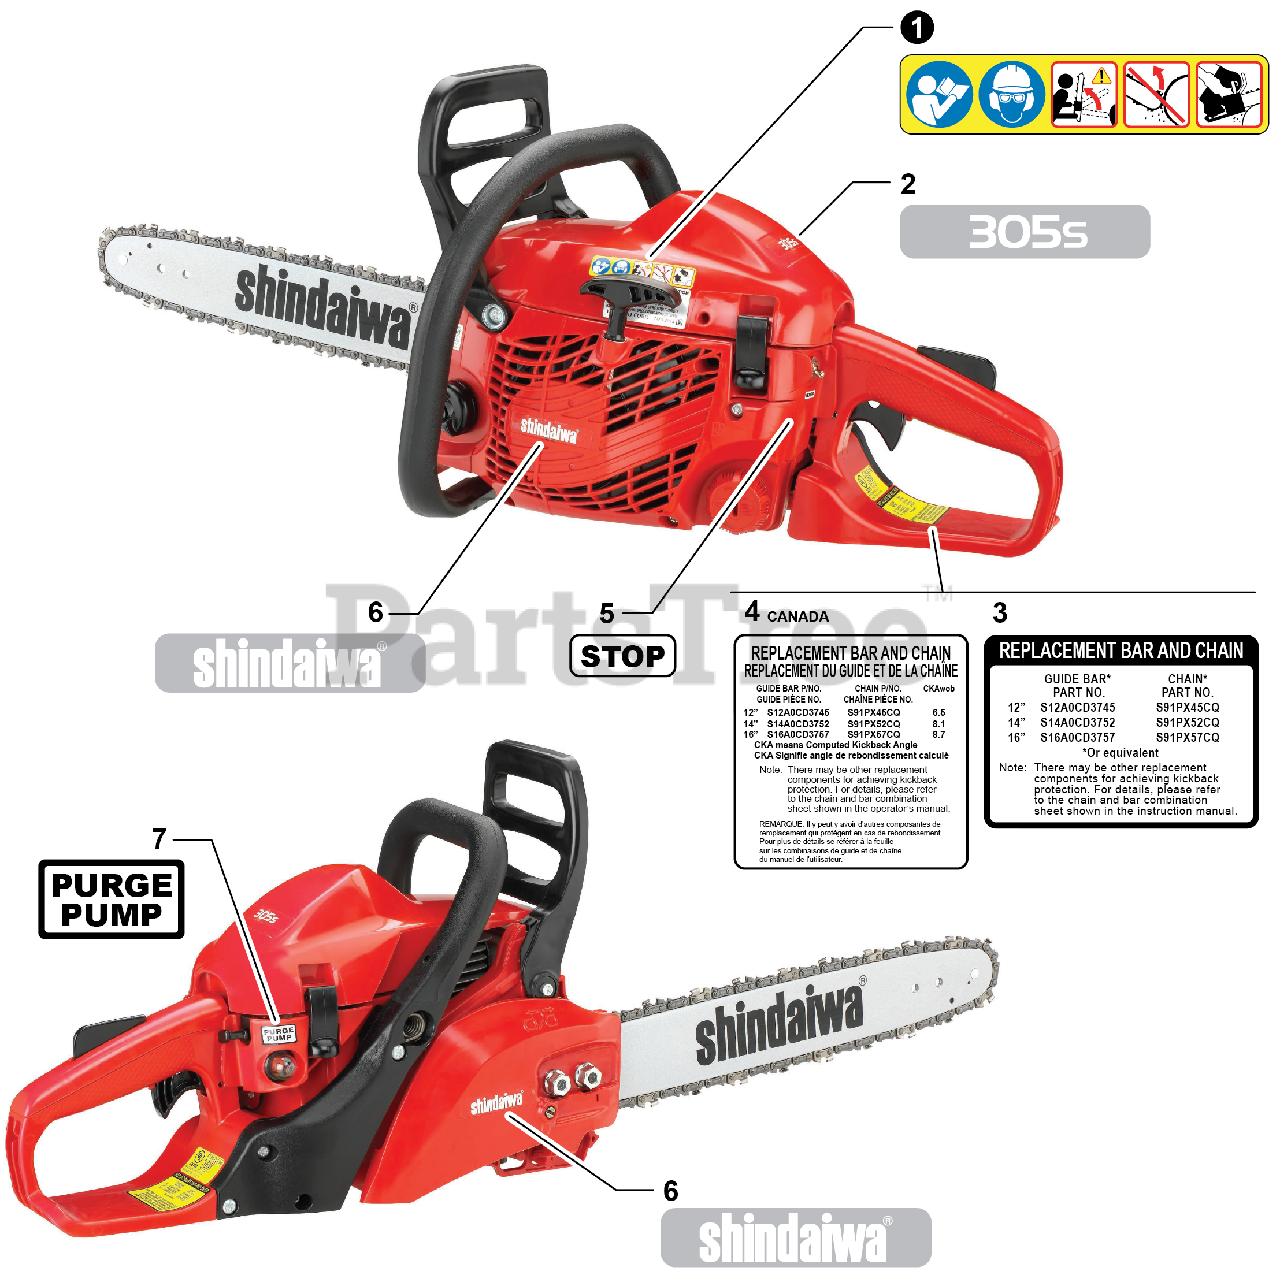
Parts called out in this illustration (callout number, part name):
1	LABEL, CAUTION
2	LABEL, MODEL - 305s
3	LABEL, BAR & CHAIN
4	LABEL, BAR & CHAIN
5	LABEL, STOP
6	LABEL - shindaiwa
7	LABEL, PURGE PUMP
